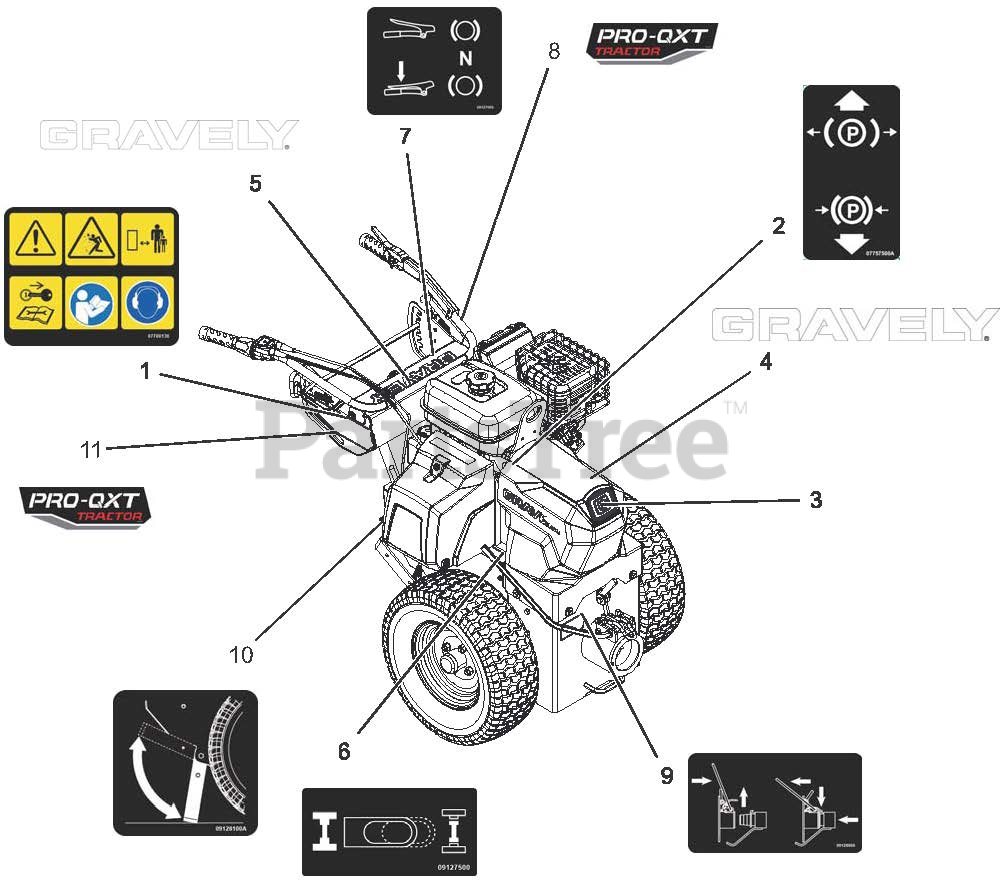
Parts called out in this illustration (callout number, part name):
1	DECAL, SAFETY DASH
2	DECAL, PARKING BRAKE LEVER
3	DECAL, GRAVELY BRAND
4	DECAL, 9.5" GRAVELY LOGO
5	DECAL, 13.5" GRAVLEY LOGO
6	DECAL, TRANSAXLE BYPASS
7	DECAL, OPERATOR CONTROLS
8	DECAL, LH PRO-QXT
9	DECAL, ATTACHMENT LOCK
10	DECAL, STAND OPERATION
11	DECAL, RH PRO-QXT
